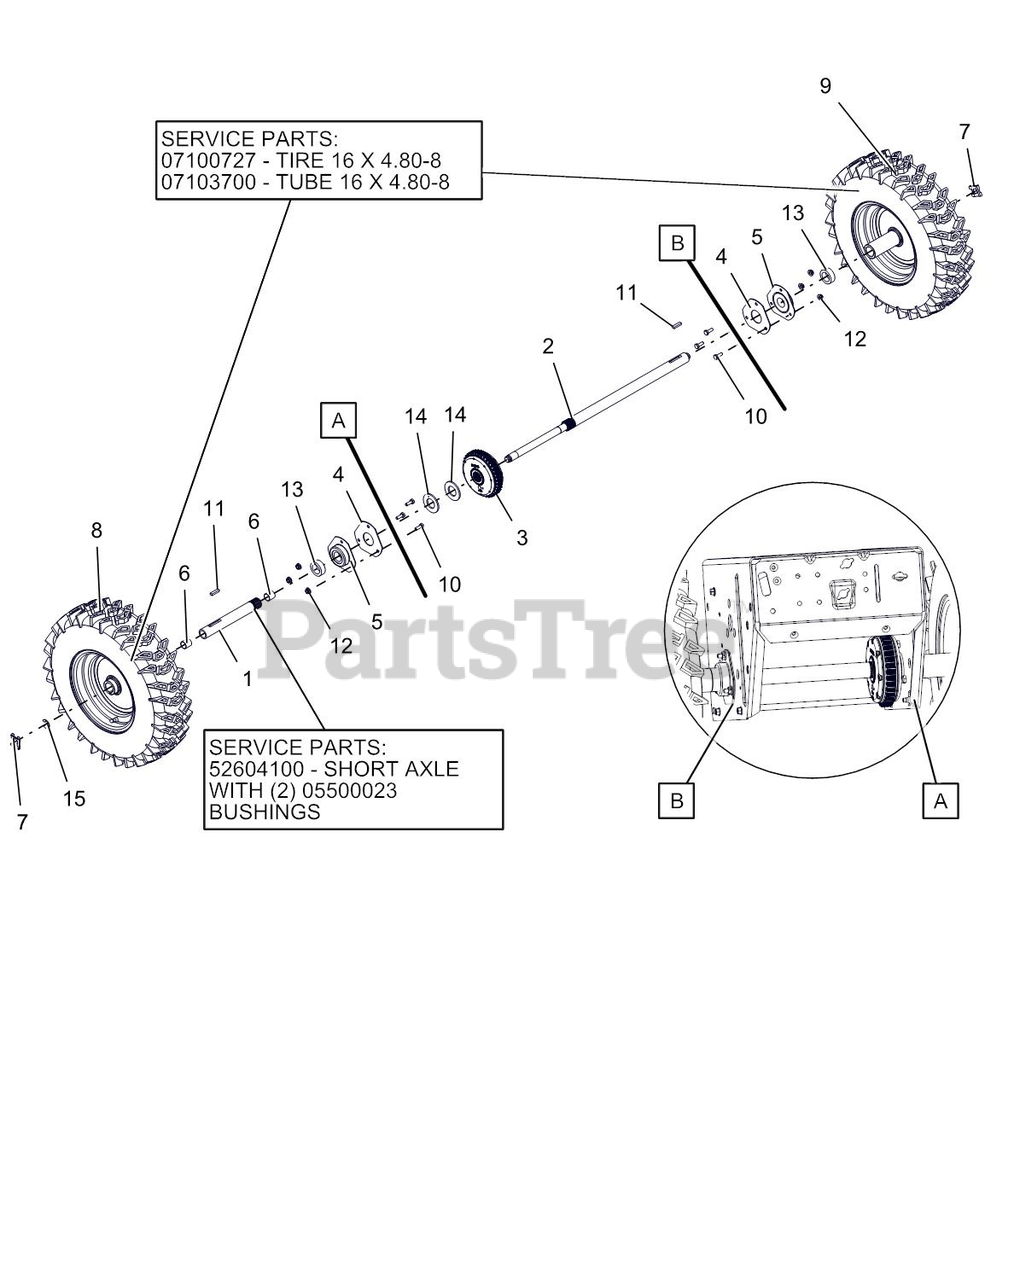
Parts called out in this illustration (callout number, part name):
1	BSHG-SLV .706X.764X.75 BRZ
1	AXLE, SHORT-PRO AUTO DIFF
1	AXLE, SHORT-AUTO W/BUSHINGS
2	AXLE, LONG-PRO AUTO DIFF
3	DIFFERENTIAL, AUTOMATIC
4	PLATE, BEARING SPACER
5	BRG-FLG 1.003/1.000 3 BOLT
6	BSHG-SLV .706X.764X.75 BRZ
7	CLIP, SNAP .625 DIA
8	TIRE/WHEEL,RH 16X4.8-8 DIFF T2
9	TIRE/WHEEL,LH 16X4.8-8 DIFF T2
10	@BLT-HEX .25-20X.75 GR5 YWZC
11	KEY-RECT .25X.188X1.00
12	@NUT-LK-CTR-FLG .25-20 YWZC
13	SPACER, PRO AXLE BEARING
14	WSHR-FL-STL- 1.062X2.0X.134 YZ
15	RG-RTNG-EXT .625X.042
16	TIRE, 4.80-8 K478
17	TUBE
